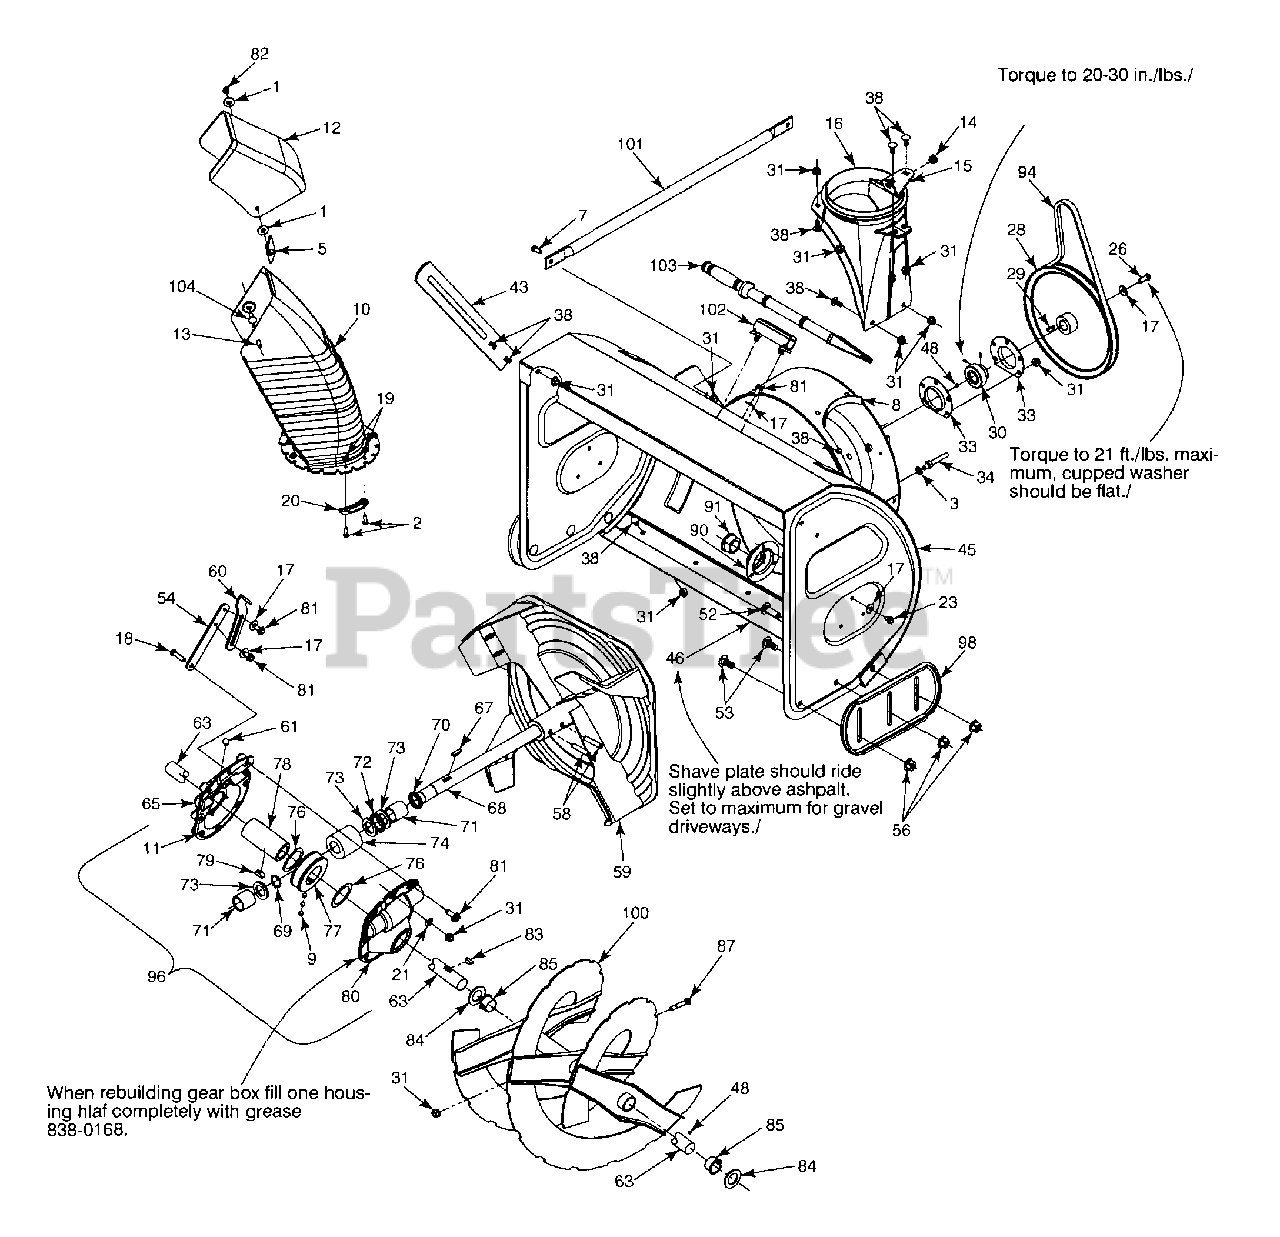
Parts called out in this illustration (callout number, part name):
1	Flat Washer .344 ID x .875 OD
2	Hex. Scr. 1/4-20 x 1.00 Gr. 5
3	Lockwasher 3/8" ID
5	Handle Knob Assembly
7	Hex Hd Cap Scr. 5/16-18 x .75 Gr. 5
10	Extended Lower Black Plastic Chute
11	Ultra Grey Loctite #5699
12	Upper Black Plastic Chute
13	Carriage Bolt 5/16-18 x 1.00" Lg
14	Plastic Bushing .380 ID
16	Chute Adapter
17	Cupped Washer.345 ID x .88 OD x .06
18	Hex Screw 5/16-18 x 1.25
19	Hex Cent. L-Nut 1/4-20 w/flange Gr. F
20	Chute Flange Keeper
21	Lockwasher 5/16" ID
22	Flange L-Nut 5/16-18 Gr. 5 Nylon
23	Hex Wash HD Tap Scr 5/16-18 x .75
26	Hex Screw 5/16-18 x .88
28	1/2" V-Pulley.875 ID x 10.12 OD
29	#9 HI-Pro Key 3/16 x 3/4 Dia HT
30	Self-Aligning Bearing .875 ID
31	Hex Flg. L-Nut 5/16-18 Gr. F Nylon
33	Bearing Housing
34	Belt Keeper Studs 3/8-16 x 2.75
38	Carriage Bolt 5/16-18 x .75
45	Snowthrower Housing Ass'y, Auger; 28" Standard Serrated
48	Arctic Grease
52	Carriage Bolt 3/8-16 x 1.00 Gr. 5
53	Carriage Bolt 3/8-16 x .75" Lg.
56	Hex Flange L-Nut 3/8-16 Gr. F Nylon
58	Spring Spirol Pin Heavy - 5/16 dia x 1.7
61	Barbed Plug
63	Spiral Axle - Auger Shaft; 28" Standard Serrated, Heavy Duty w/brace
63	Spiral Axle - Auger Shaft; 30" Standard Serrated, Heavy Duty w/brace
63	Spiral Axle - Auger Shaft; 33" Standard Serrated, Heavy Duty w/brace
63	Spiral Axle - Auger Shaft; 45" Heavy Duty w/brace
65	Gear Housing Half - RH
67	#9 HI-Pro Key 3/16 x 3/4 Dia HT
68	Auger Drive Shaft
69	Snap Ring for.875 dia. shaft
70	Oil seal for .875 ID Garlock (76 x 6133)
71	Sleeve Bearing .875 ID
72	Thrust Bearing .88 ID x 1.44 OD x .078
73	Flat Washer.88 ID x 1.4 OD x.1 25
74	Worm Gear LH Double Thread
76	Flat Washer 1.5 ID x 2.0 OD x .03
77	Worm Gear LH Double Thread (Bronze)
78	Worm Gear Shaft
79	#91 Woodruff Key 1 /4 x 3/4 Dia.
80	Gear Housing Half LH
81	Hex Flange Scr. 5/16-18 x .75
82	Hex Ins. L-Nut 5/16-18
83	#91 Woodruff Key 1/4 x 3/4 Dia.
84	Flat Washer
85	Flange Bearing
87	Shear Bolt 5/16-18 x 1.75
91	Flange bearing w/flats
94	V-Belt 1/2 x 44" Lg.
96	Worm Gear Box Ass'y
103	Cleanout Tool
104	Carriage Bolt 5/16-18 x 1.75
838-0168	Grease
